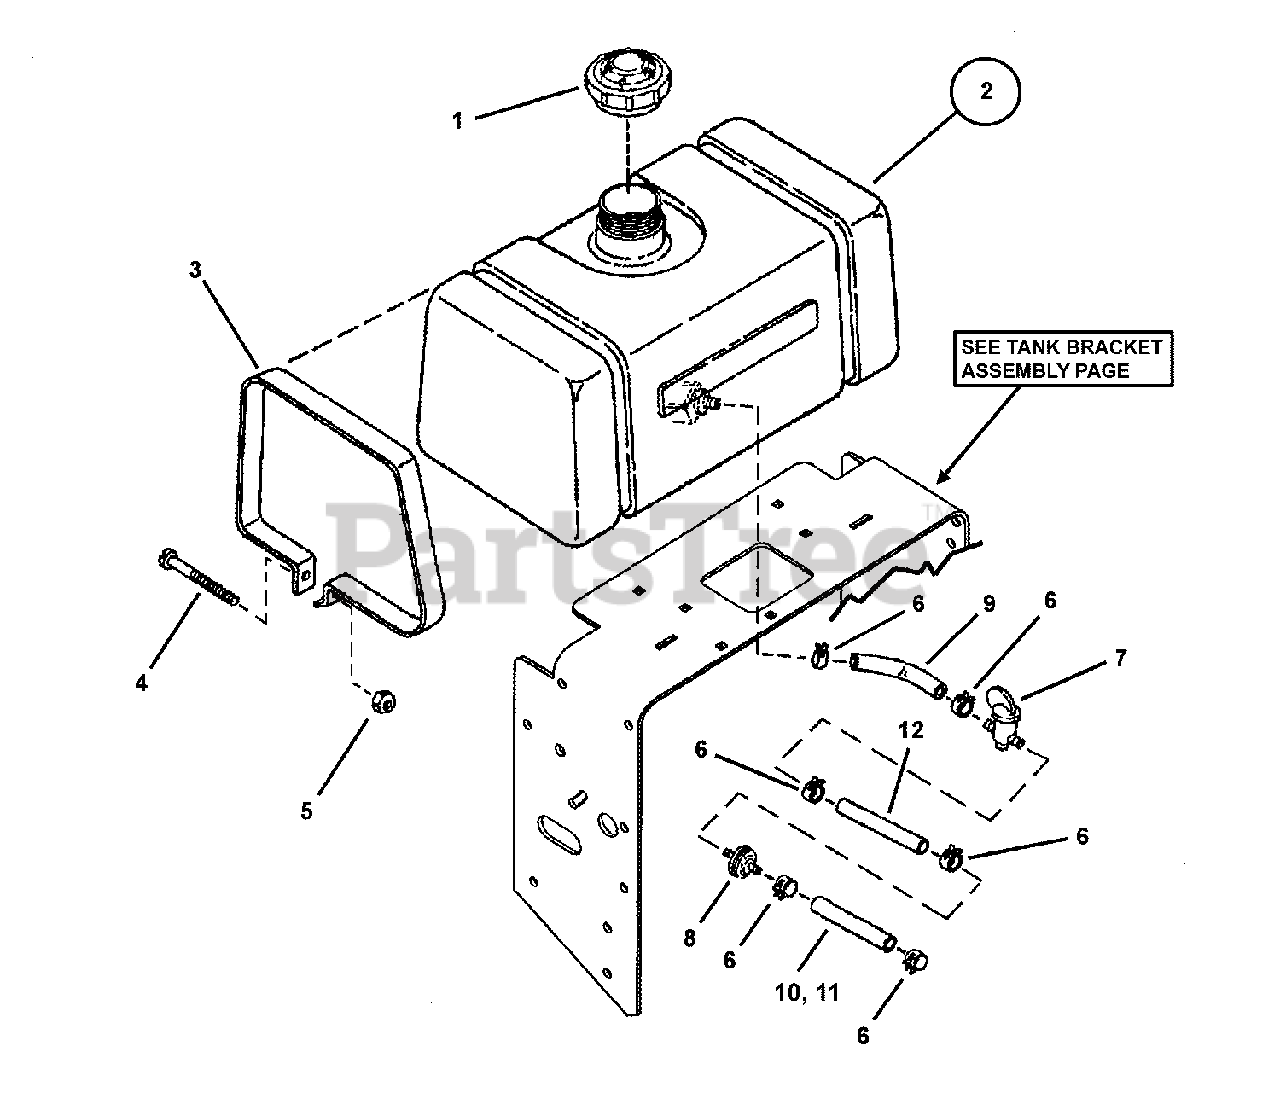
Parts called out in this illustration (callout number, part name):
1	CAP, Fuel Tank
2	FUEL TANK
3	STRAP, Tank
4	SCREW, #10-24 x 2-1/2" Pan Head Machine
5	NUT, #10-24 Hex Nyloc
6	CLAMP, Fuel Hose
7	VALVE, Fuel
8	FILTER, In-Line
9	* LINE, Fuel (1/4" I.D. x 10" Long)
10	* HOSE, Fuel (1/4" I.D. x 6-1/2" Long)
12	* HOSE, Fuel (1/4" I. D. x 5" Long)
